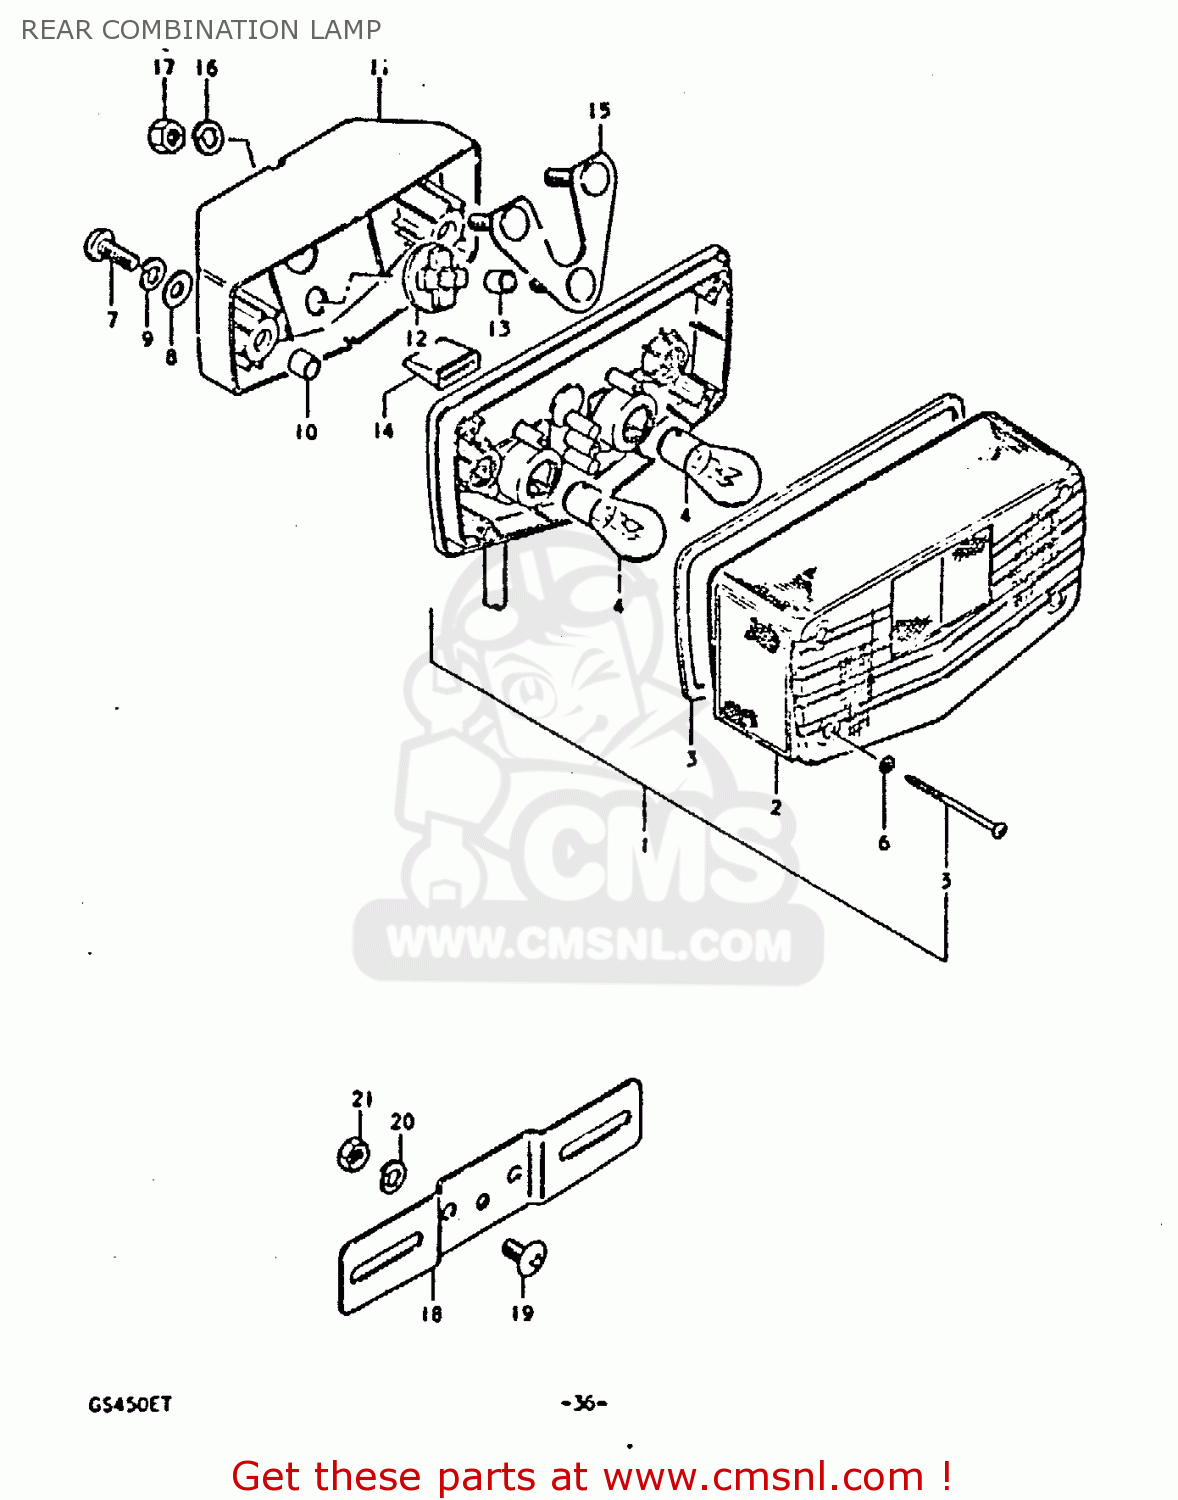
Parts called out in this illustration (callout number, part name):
1	LAMP UNIT,REAR COMBINATION
2	LENS,REAR COMBINATION LAMP
3	GASKET,REAR COMBINATION LAMP LENS (NAS)
4	BULB(12V23W)
5	SCREW
6	GASKET (NAS)
7	SCREW
8	WASHER
9	LOCK WASHER
10	SPACER,REAR COMBINATION LAMP
11	BRACKET UNIT,TAIL LAMP
12	CUSHION,REAR COMBINATION LAMP
13	SPACER,REAR COMBINATION LAMP
14	CUSHION,REAR COMBINATION LAMP
15	PLATE,REAR COMBINATION LAMP
16	LOCK WASHER
17	NUT
18	PLATE,RR LICENSE
19	SCREW
20	LOCK WASHER
21	NUT
